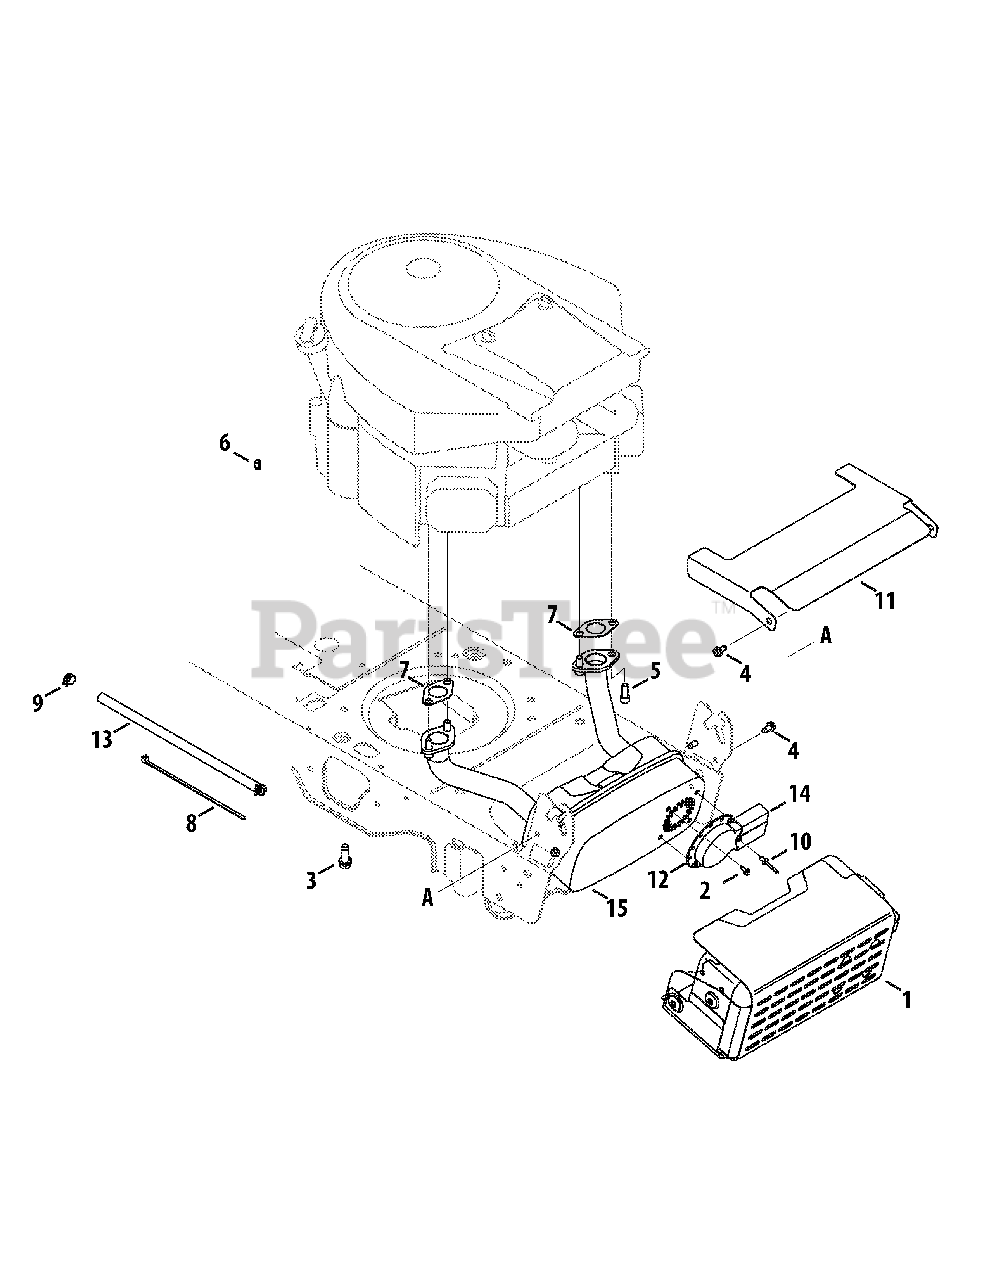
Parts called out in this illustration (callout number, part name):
1	Mulffler Shield Assembly
2	Screw, Indented Washer, #8-18:0.500
3	Taptite Screw, Indented Washer, 3/8-16:1.000
4	Taptite Screw, Indented Washer, 1/4-20:0.500
5	Socket Head Screw, 5/16-18:.750
6	Sems Nut, 1/4-20
7	Exhaust Gasket
8	Cable Tie, 3/16 x .05 x 7.4
9	Hose Clamp, .490 DIA.
10	Rivet, .188 DIA x .300 L
11	Heat Shield
12	Muffler Deflector
13	Fuel Hose
14	Long Muffler Deflector
15	Muffler Deflector
